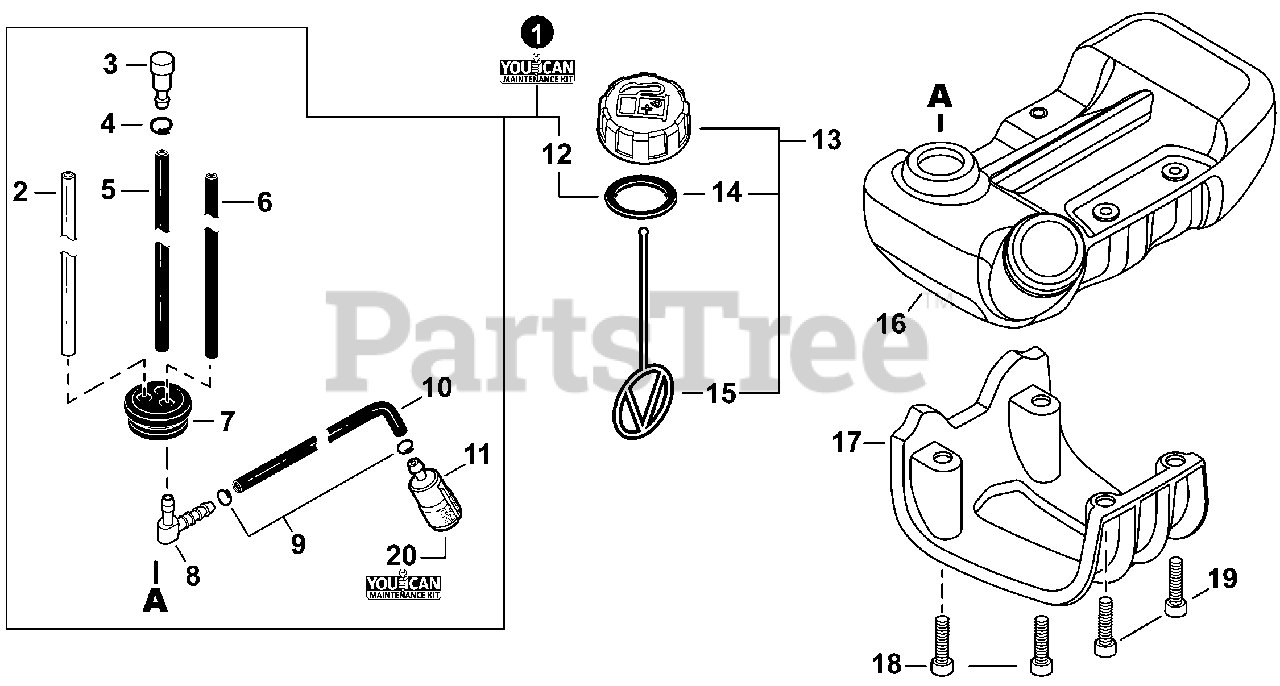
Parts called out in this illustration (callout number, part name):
1	FUEL SYSTEM KIT - YOUCANT
2	PIPE, FUEL 3x6x85 CLEAR
3	VENT ASSY
4	CLIP 6.5 MM
5	PIPE, FUEL 3x6x95 BLACK
6	PIPE, FUEL 3x5.5x70 BLACK
7	GROMMET, FUEL
8	CONNECTOR, PIPE
10	PIPE, FUEL 3x5x140x35 BLACK
11	FILTER, FUEL
12	GASKET, FUEL CAP
13	CAP ASSY, FUEL
14	GASKET, FUEL CAP
15	CONNECTOR, CAP L= 123
16	TANK, FUEL
17	GUARD, FUEL TANK
18	BOLT, TORX 5x25
19	BOLT, TORX 5x20
20	TUNE-UP KIT - YOUCANT
